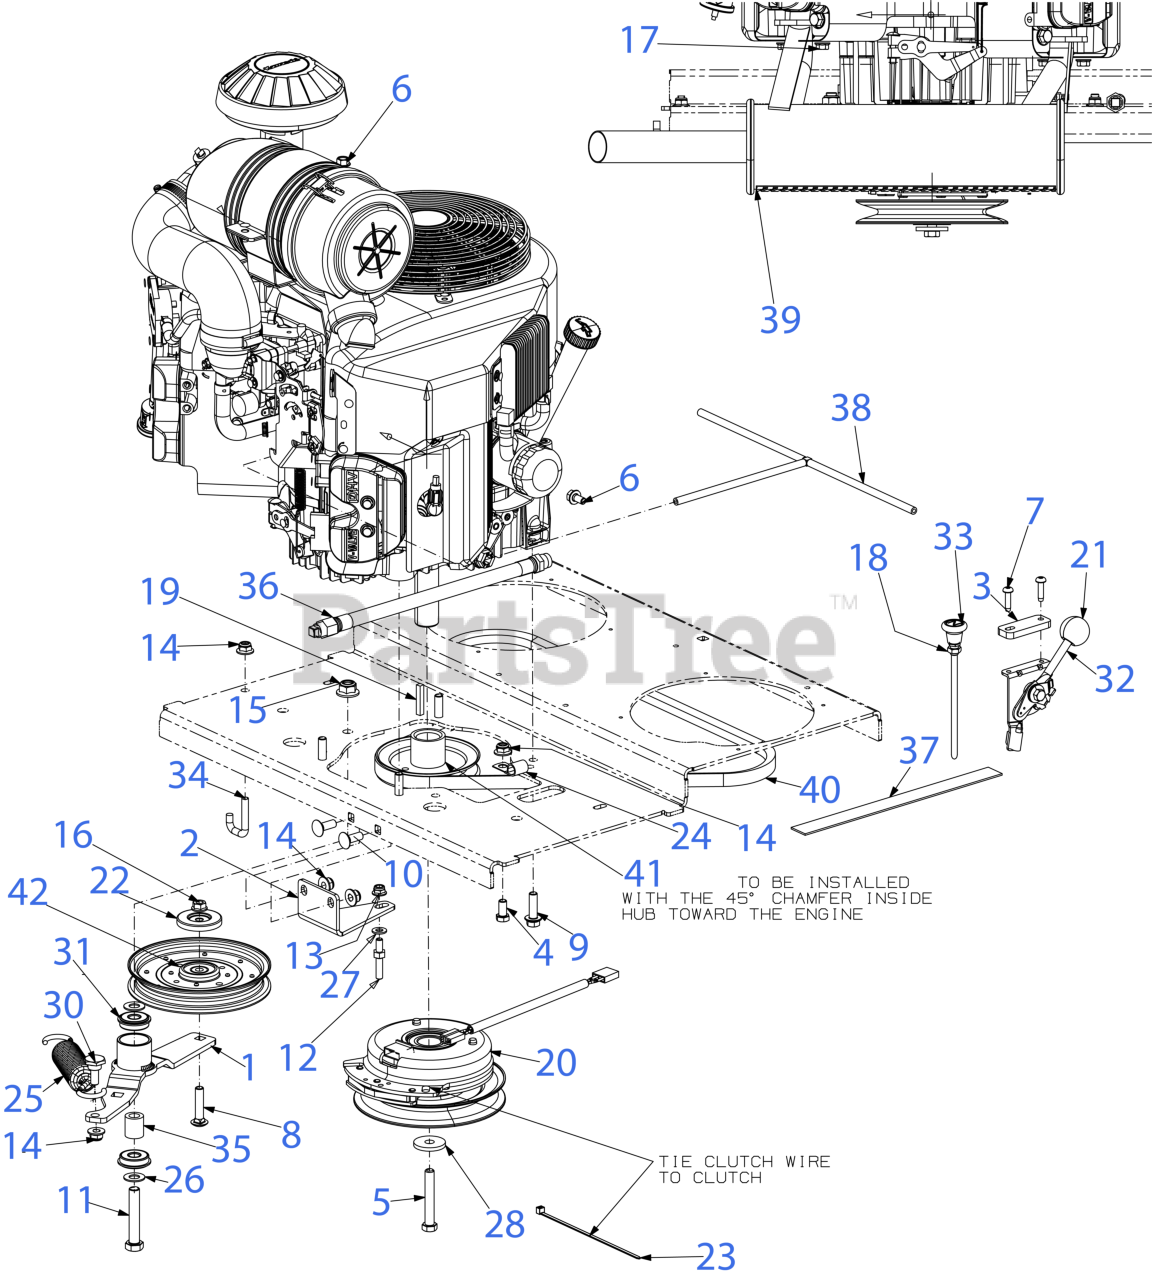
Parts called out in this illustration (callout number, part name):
1	TRANSMISSION IDLER BRACKET
4	HEX SCREW 3/8-16 x .75
5	SCREW 7/16-20:2.75 GR5
6	SCREW M8 x 1.25 x 16MM GR8.8
7	SCREW 1/4-20 x 1.0
8	CARRIAGE BOLT 3/8-16 x 1.75 GR5
9	SCREW 3/8-16 x 1.25 GR5
10	CARRIAGE BOLT 3/8-16 x 1.00 GR5
11	SCREW 1/2-13 x 2.75 GR5
13	FLANGE LOCK NUT 5/16-18
16	HEX LOCK NUT
17	HEX FLANGE NUT
18	HEX JAM NUT 3/8X24
19	SQUARE KEY 1/4 x 1.50
20	ELECTRIC PTO CLUTCH
22	PULLEY CAP
23	7" CABLE TIE
24	J TYPE CLIP
25	EXTENSION SPRING W/HOOK
26	FLAT WASHER .510 x .995
27	FLAT WASHER
28	FLAT WASHER .45 x 1.5 x .172 HT
30	SHOULDER SCREW .625 x .302 x 3/8-16
31	ROLLER BEARING .5X1.37X.44
32	THROTTLE CABLE 59"
33	CHOKE CABLE
34	ROD SPRING HOOK
35	SPACER 0.51 x 0.88 x 1.00
36	OIL DRAIN HOSE
37	HEAT SHIELD 24"
38	ROLLOVER VENT HOSE ASSEMBLY
39	KAWASAKI MUFFLER
40	TRANSMISSION BELT
41	PULLEY - PUMP DRIVE
42	IDLER PULLEY
